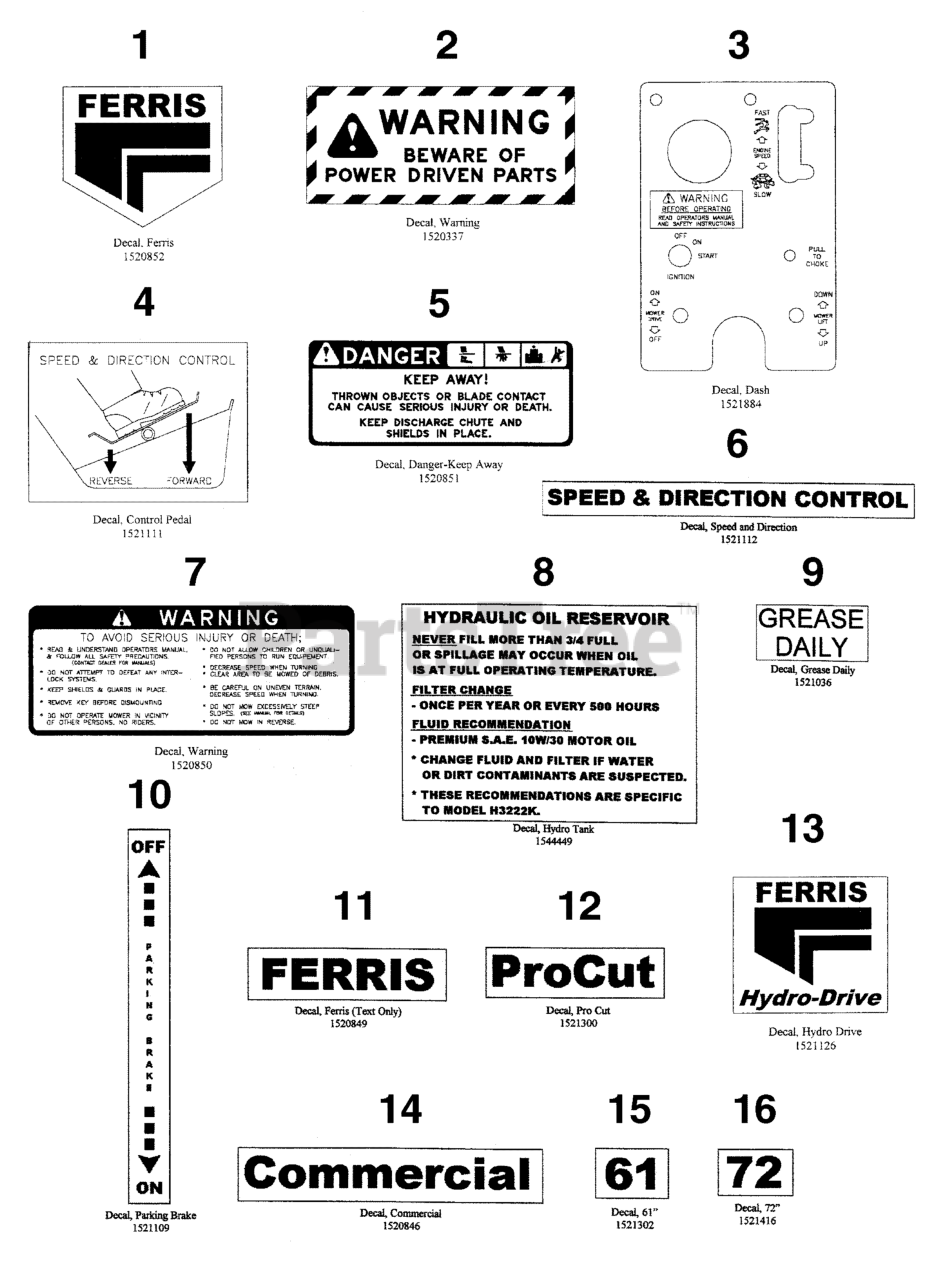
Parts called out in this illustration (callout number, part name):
1	DECAL, Ferris Logo, 10-3/4"
2	DECAL, Warning
3	DECAL, Dash
4	DECAL, Speed Control
5	DECAL, DANGER DO NOT OPERATE W/O DEFLECT
7	DECAL, WARNING Operation
8	DECAL, Oil Reservoir
9	DECAL, Grease Daily
10	DECAL, PARKING BRAKE-RIDER
11	DECAL, FERRIS TEXT & LOGO
12	DECAL, ProCut
13	DECAL, Hydro-Dirve
14	DECAL, Commerical
15	DECAL, 61"
16	DECAL, 72"
